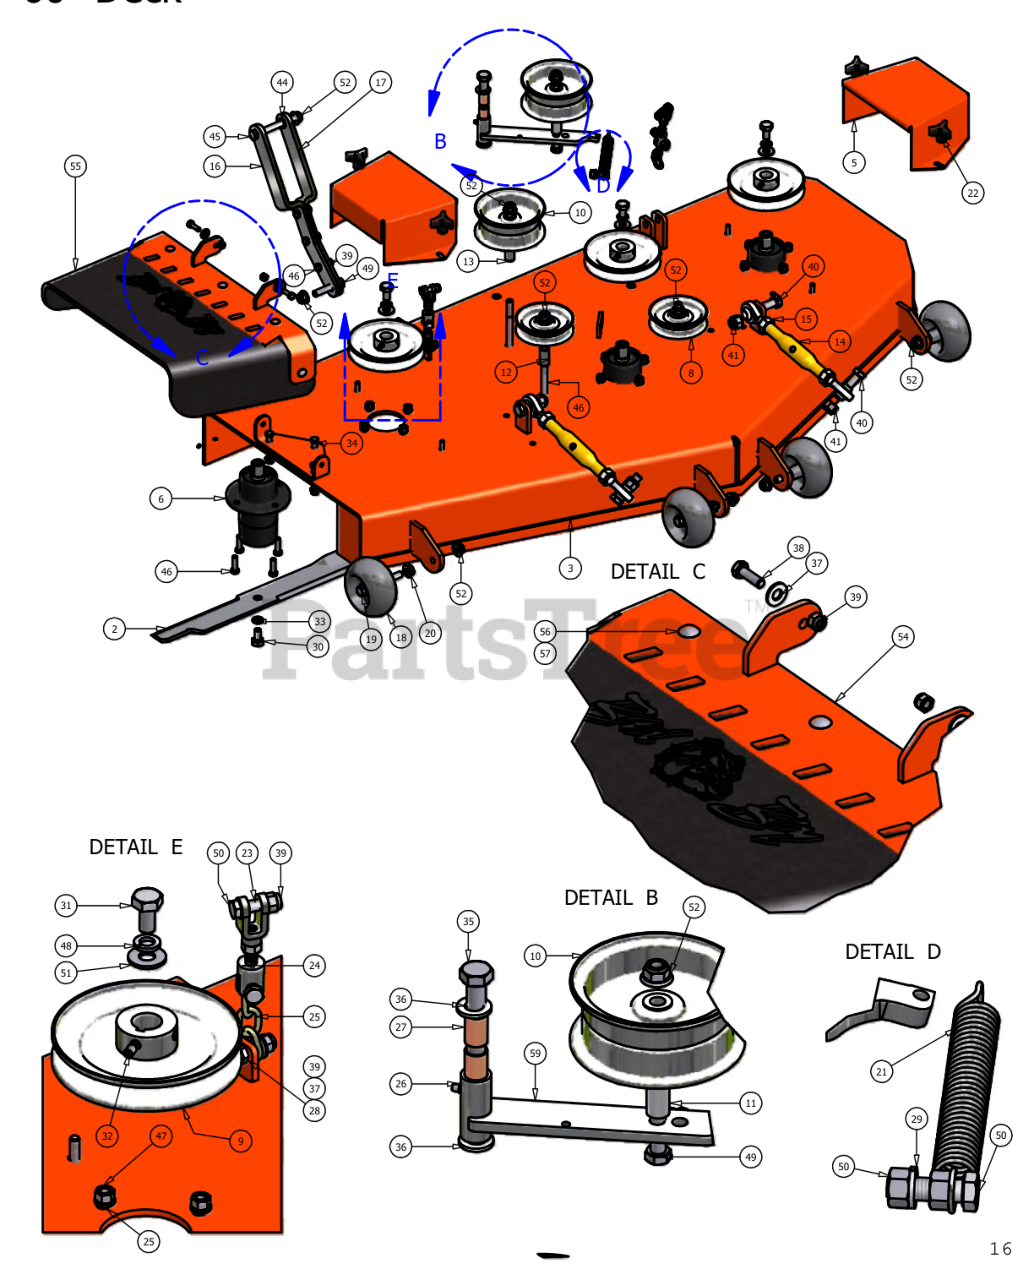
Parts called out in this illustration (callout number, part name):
1	60" Deck Belt
2	60" Fusion Blade
4	Dischage Chute Hander
5	Pulley Guard
7	Deck Idler Pully
8	4 3/4" Idler Pulley
9	6 1/4" Drive Pulley
10	5 3/4" Flat Idler Pulley
11	1 1/4" Pulley Spacer
12	Pup Pulley Spacer
13	1 3/4" Pulley Spacer
14	Turnbuckle
15	3/4" Left Hand Nut
16	Deck Support Arm (Left)
17	Deck Support Arm(Right)
18	Anti-Scalp Roller
19	1/2"x4" Bolt (Grade8)
20	1/2" Flange Nut
21	Deck Idler Spring
22	5/16" Knob
23	Female Yoke
26	Grease Fitting
27	5/8" ID x 1 1/8" Brass Bushing
28	3/8" x 1" Hex Bolt
29	5/8" x 1 1/2" Fine Threaded Bolt
30	3/8" Lock Washer
31	1/2" x 1 1/2" Bolt
32	3/8" Set Screw
33	5/8" Lock Washer
34	3/8" x 3/4" Hex Bolt
35	5/8" x 4" Hex Bolt
36	.635 ID Plastic Washer
37	.360 Id Plastic Washer
38	5/16" x 1" Hex Bolt
39	5/16" Nylock Nut
40	5/8" x 2 1/2" Bolt
41	5/8" Nylock Nut
42	1/2" x 3 1/2" Hex Bolt
43	1/2" Brass Washer
44	1/2" x 4 1/2" Bolt
45	3/8" x 1 1/4" Hex Bolt
46	3/8" Hex Nut
47	1/2" Lock Washer
48	1/2" x 2 1/2" Hex Bolt
49	3/8" x 1 1/2" Hex Bolt
50	1/2" Cupped Washer
51	1/2" Flange Lock Nut
52	2007 Lower Hanger
53	2007 Hanger Plate
54	Rubber Side Discharge
55	5/16" x 1 1/2" Carriage Bolt
56	5/16" Nylock Flange Nut
57	1/2" x 3" Bolt
58	3/8" Flange Nut
59	3/8" Flat Washer
